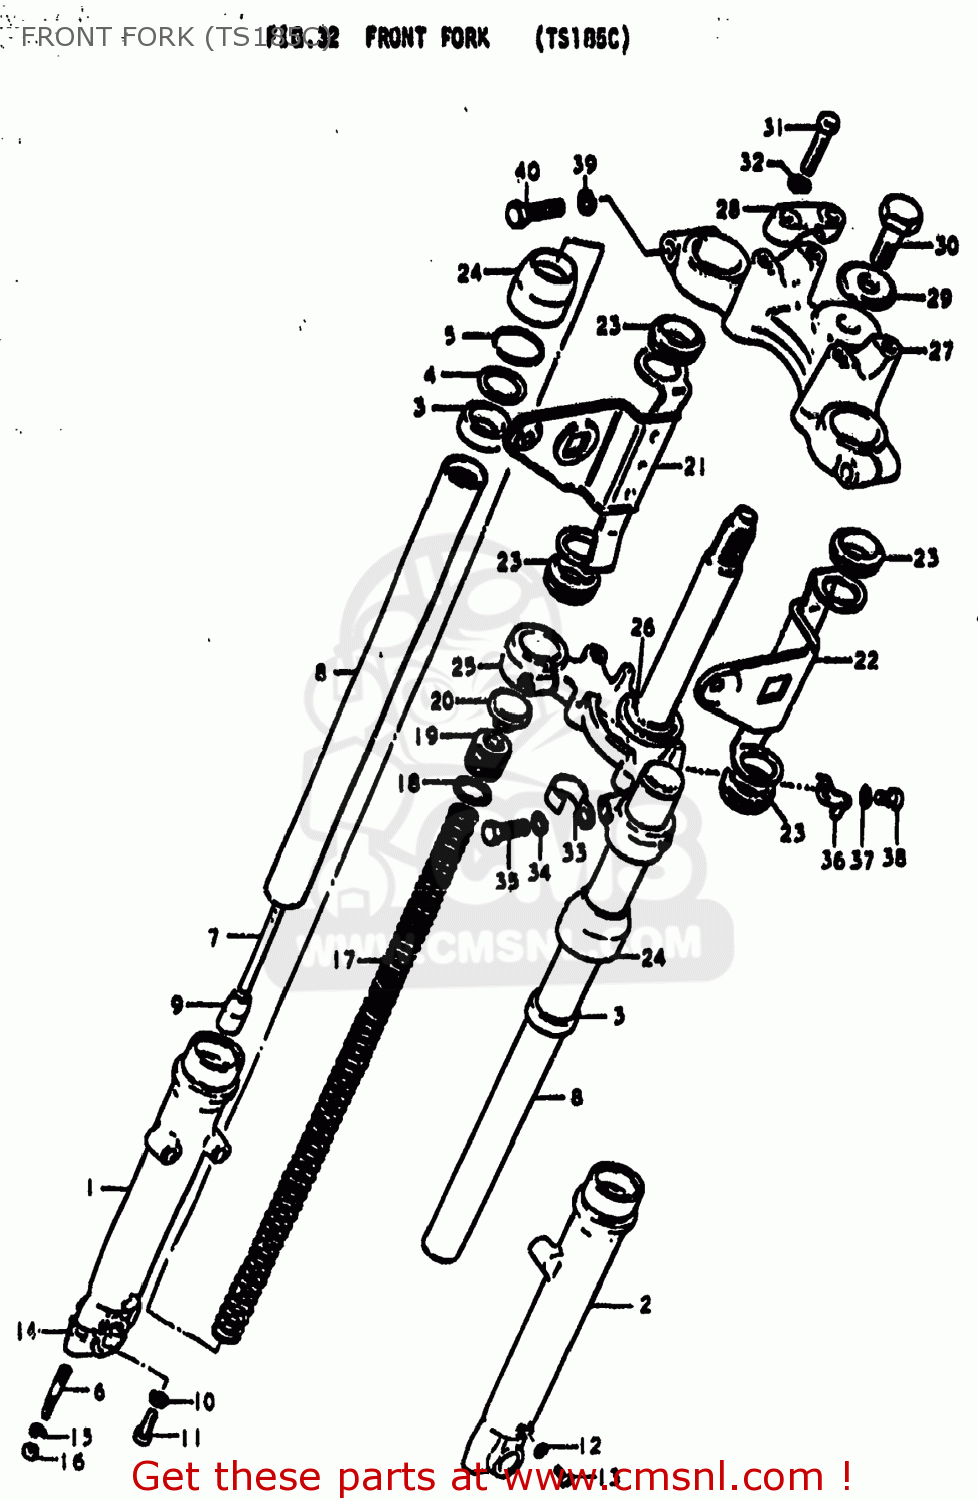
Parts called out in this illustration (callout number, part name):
1	TUBE,FORK,OUTER,RIGHT
2	TUBE,FORK,LEFT,OUTER
3	OIL SEAL,FRONT FORK
4	WASHER,FRONT FORK
5	RING,SNAP
6	STUD BOLT
7	CYLINDER,FRONT FORK
8	TUBE,FORK,INNER
9	PIECE,OIL LOCK
10	GASKET (NAS)
11	BOLT,FORK CYLINDER(10X25)
12	GASKET,DRAIN,PLUG (NAS)
13	SCREW
14	HOLDER,AXLE
15	LOCK WASHER
16	NUT (8MM)
17	SPRING
18	O RING
19	CAP
20	CAP,FR FORK
21	BRACKET,HEADLAMP HOUSING
22	BRACKET,HEADLAMP,LEFT
23	GASKET (NAS)
24	SEAL,DUST
25	STEM,STEERING
26	RACE,STEERING OUTER LWR
27	HEAD,STEERING STEM
28	HOLDER,HANDLE(BLACK)
29	WASHER,STEM HEAD
30	BOLT,FR FORK(10X33)
31	BOLT
32	LOCK WASHER
33	CLIP
34	WASHER,LOCK 12
35	BOLT,FR FORK LWR(12X33)
36	CLIP,BRAKE CABLE
37	LOCK WASHER
38	SCREW
39	LOCK WASHER
40	BOLT,FORK INNER TUBE F
